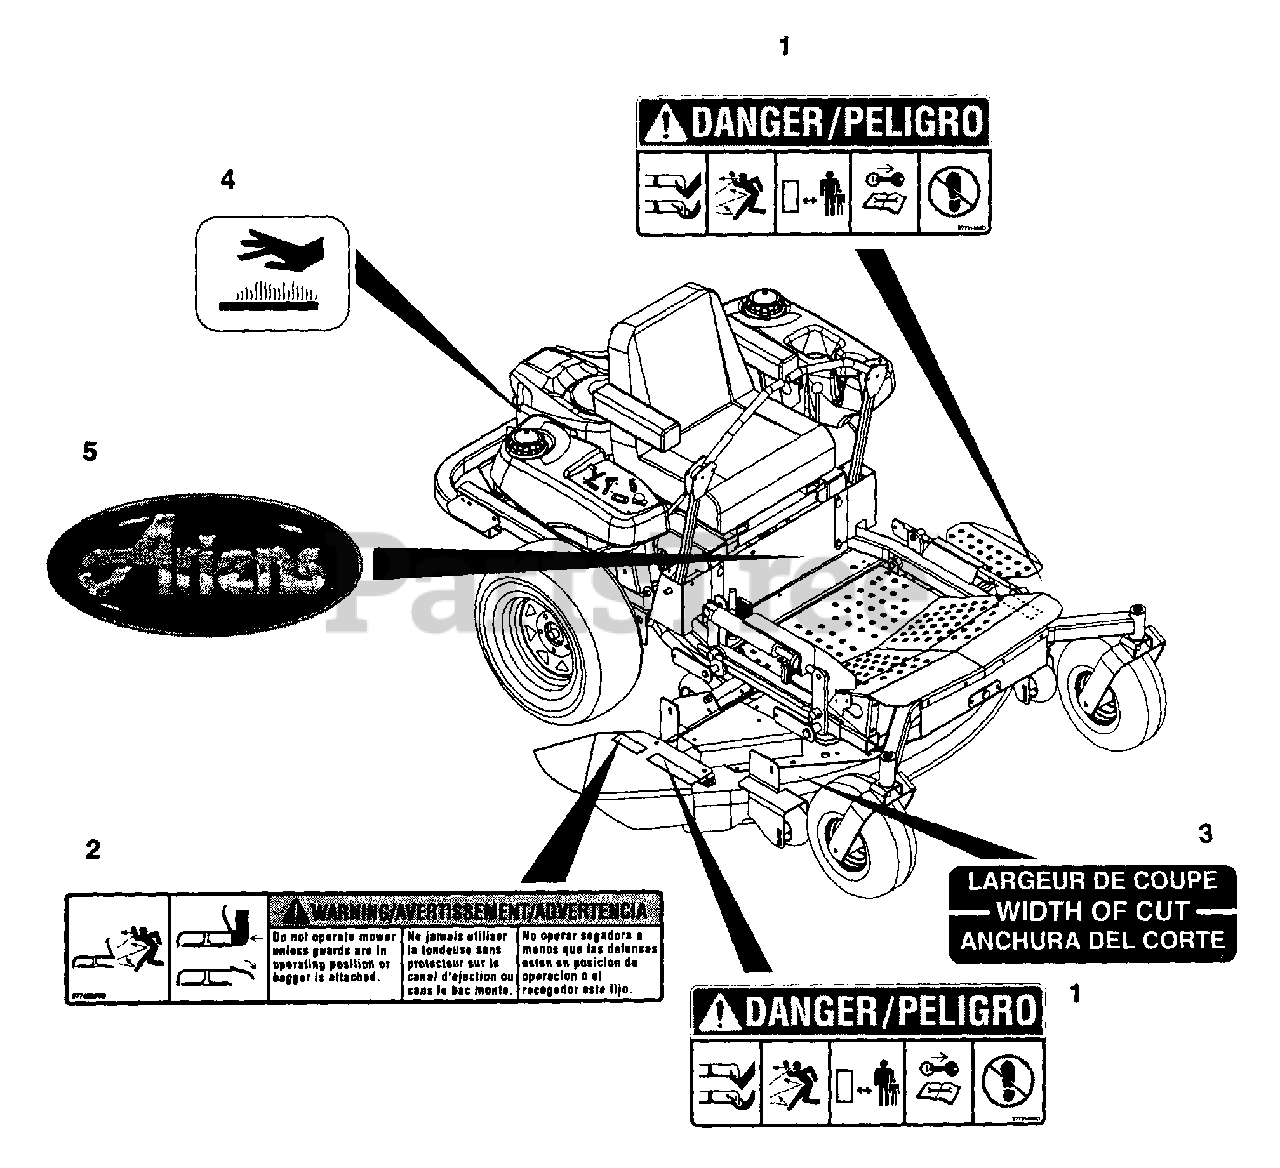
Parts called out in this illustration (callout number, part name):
1	DECAL, MOWER PAN DANGER
2	DECAL, WARNING
3	WIDTH OF CUT DECAL
4	DECAL, HOT SURFACE
5	DECAL, ARIENS JEWEL
